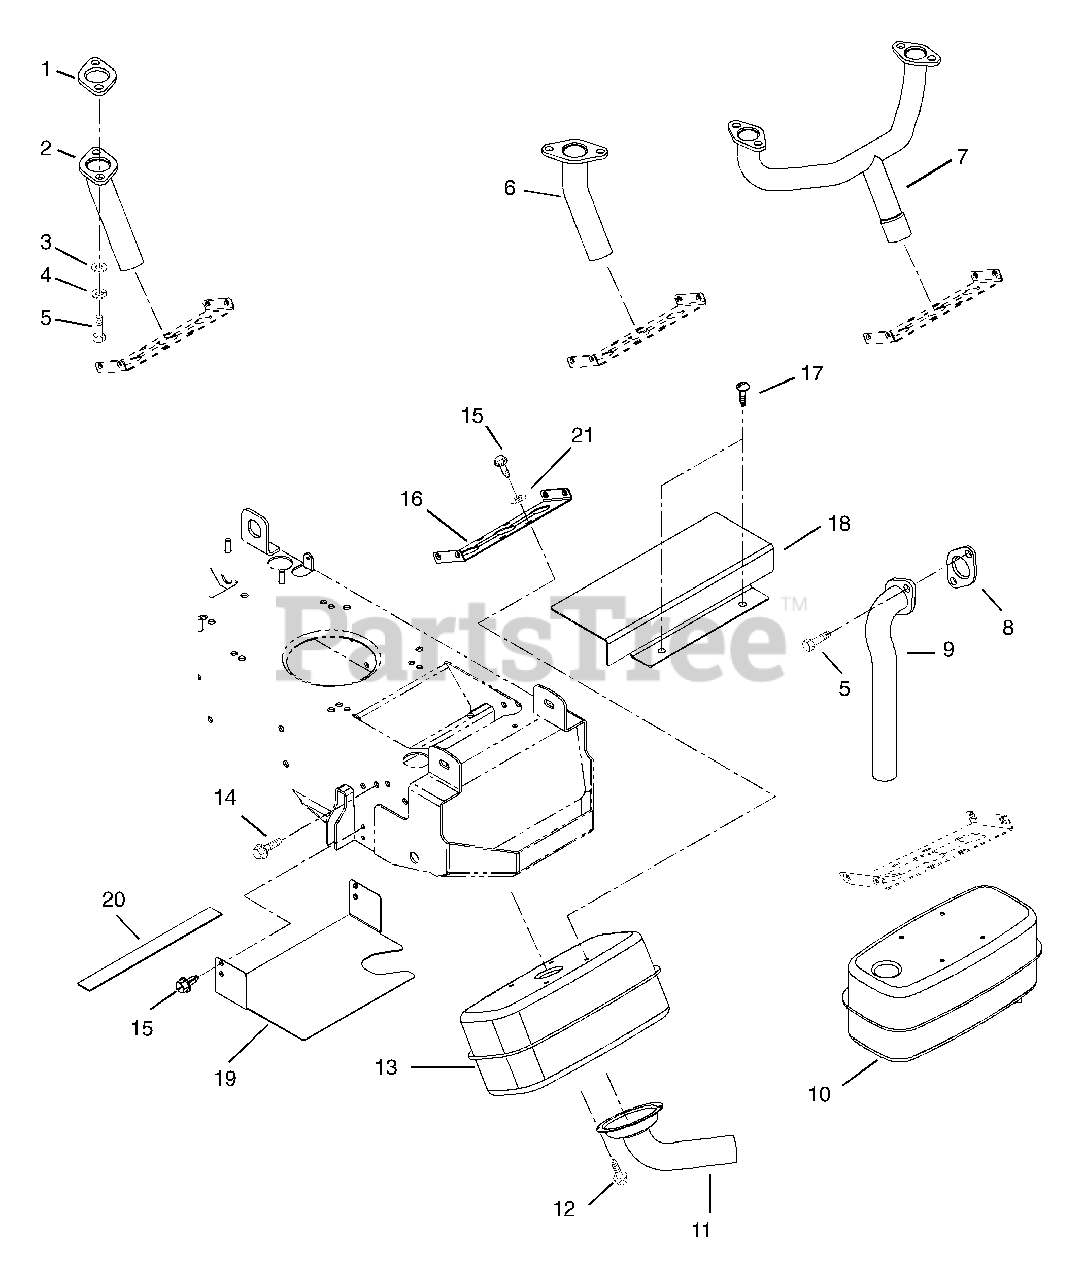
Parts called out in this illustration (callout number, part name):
1	GASKET- 12.5/13 TEC (#35-414)
2	TUBE - EXHAUST WELD. 13 HP
3	WSHR-FL-STL .323X.625X.062 YWZ
4	@WSHR-LK .31X.078 REG YWZC
5	SCR-CAP .31-18X.75 S/HD
6	PIPE - EXHAUST
7	PIPE - EXHAUST TWIN B&S
8	GASKET B&S#272293
9	PIPE - EXHAUST
10	MUFFLER W/DEFLECTOR
11	DEFLECTOR - EXHAUST
12	SCR-TAP 8-32X.38 SL HWH YWZC
13	MUFFLER - EXHAUST
14	@SCR-TAP .31-18X.50 HWH TR YWZ
15	@SCR-TAP 12-24X.75 HWH YWZC
16	BRACKET - MUFFLER
17	@SCR-TAP .31-18X.50 HWH TR YWZ
18	SHIELD - HEAT
19	SHIELD - HEAT
20	HEAT SHIELD- FABRIC 1X10.75
21	@WSHR-FL-STL.250X.56X.049 YWZC
